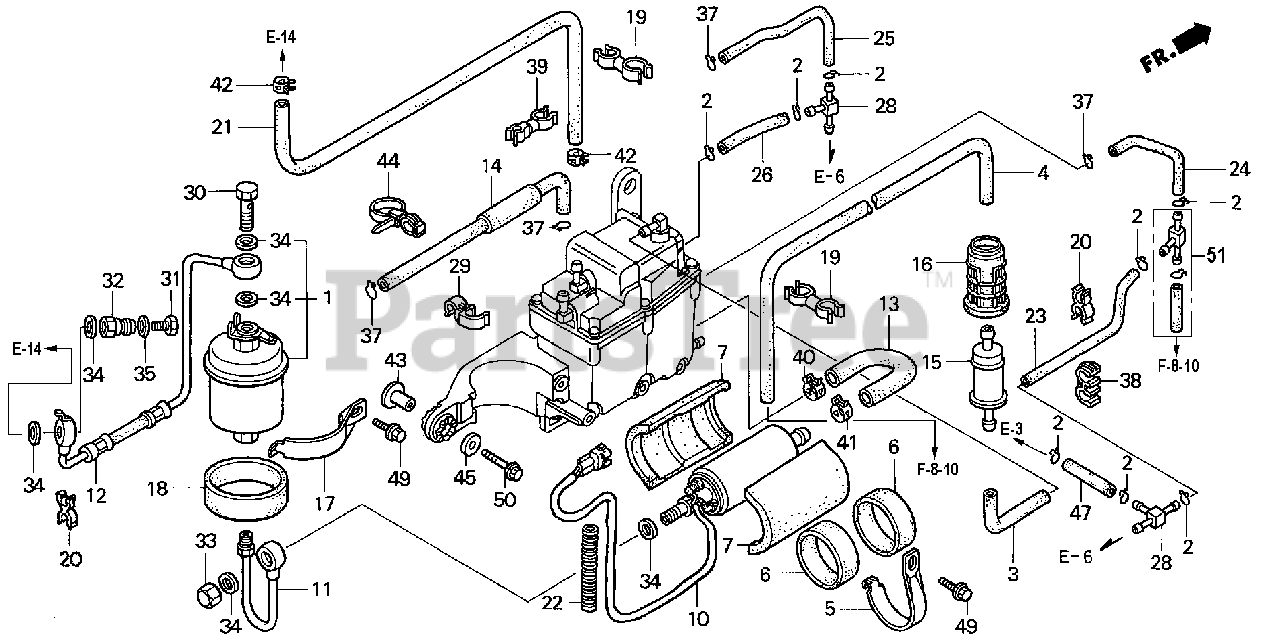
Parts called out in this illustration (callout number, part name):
1	FILTER SET, FUEL (TOYO ROKI)
2	CLIP, TUBE
3	TUBE A, AIR VENT
4	TUBE B, AIR VENT
5	BAND, FUEL PUMP
6	GROMMET, FUEL PUMP
7	INSULATOR, FUEL PUMP
10	PUMP UNIT, FUEL
11	PIPE, FUEL
12	HOSE, FUEL
13	TUBE C, FUEL
14	TUBE, FUEL (D)
15	FILTER, FUEL PUMP
16	SUSPENSION, STRAINER
17	BAND, FUEL STRAINER
18	GROMMET, FUEL STRAINER
19	CLAMP, HOSE
20	CLAMP, TUBE
21	HOSE, PRESSURE REGULATOR RETURN
22	TUBE, CORRUGATE (7MM)
23	TUBE A, WATER
24	TUBE B, WATER
25	TUBE C, WATER
26	TUBE D, WATER
28	JOINT, THREE WAY
29	CLIP, SENSOR HOSE
30	BOLT, SEALING (12MM)
31	BOLT, SEALING (6MM)
32	BOLT, FUEL PRESSURE CHECK
33	NUT A, SEALING (12MM)
34	WASHER, SEALING (12MM)
35	WASHER, SEALING (6MM)
37	CLIP, TUBE (B12)
38	CLAMP, FUEL TUBE
39	CLAMP (6MM-12MM)
40	CLAMP, TUBE (D15)
41	CLAMP, TUBE (D17)
41	CLAMP, FUEL TUBE (D17.0)
42	CLAMP, TUBE (D10.7)
43	COLLAR (8.3X14.5)
43	COLLAR (8.5X14.5)
44	CLIP, TUBE (135MM) (BLACK)
45	WASHER, PLAIN (8MM)
47	BULK HOSE, VACUUM (7X3000) (7X100)
49	BOLT, FLANGE (6X14)
50	BOLT, FLANGE (8X35)
51	JOINT SET, THREE WAY
